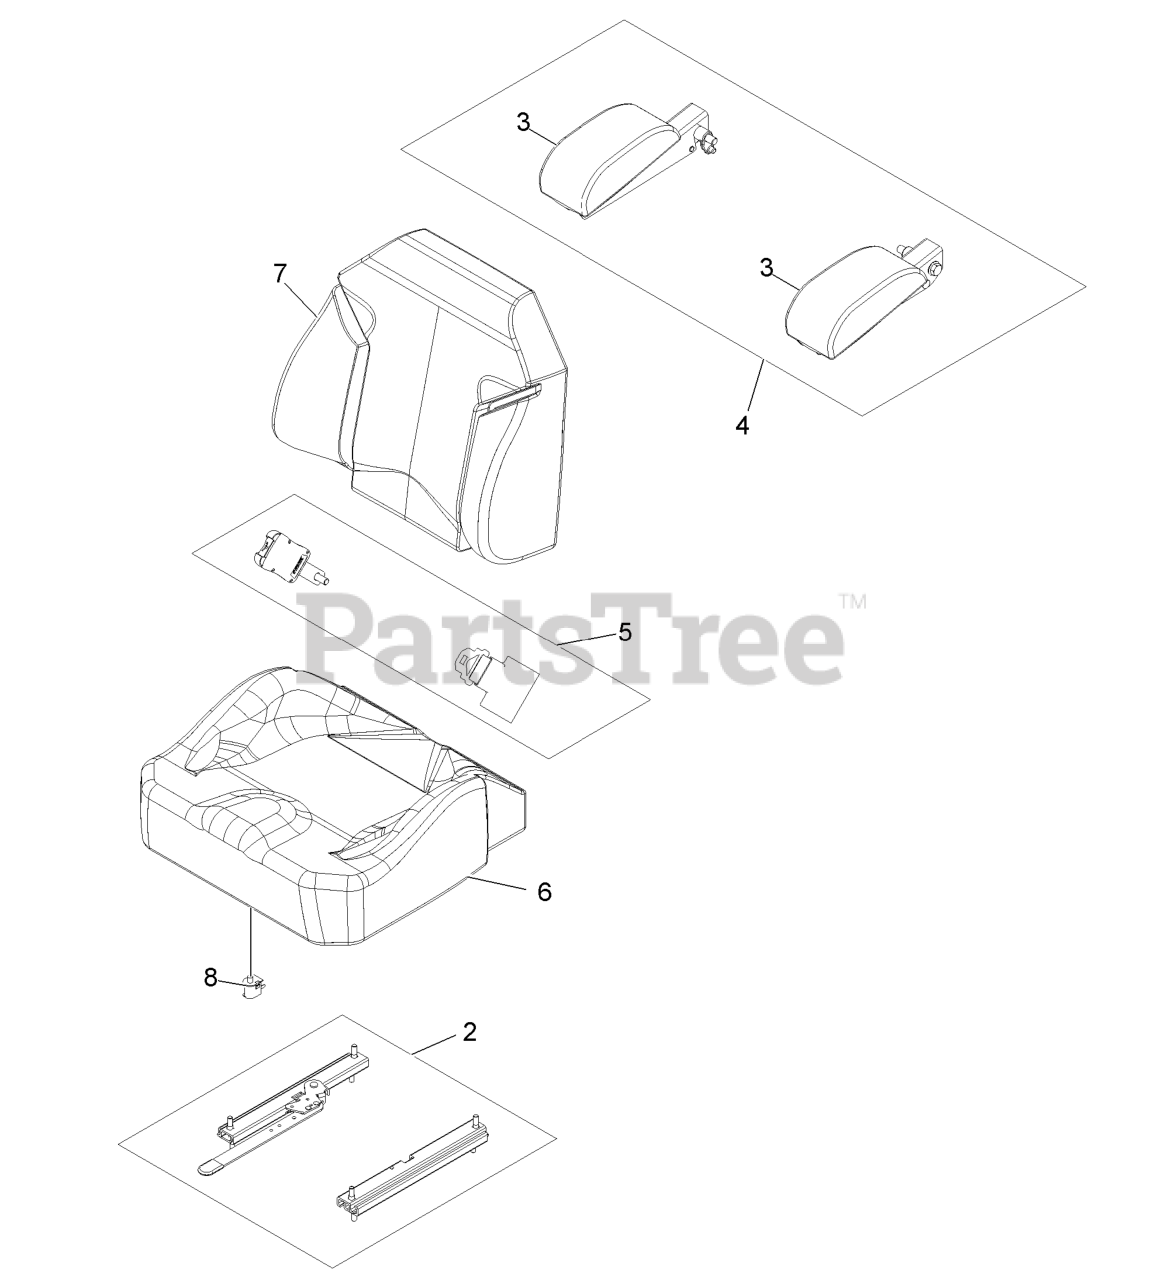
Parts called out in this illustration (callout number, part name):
2	SEAT TRACK SET
3	ARM REST PAD SET
4	ARM REST SET
5	SEAT BELT KIT
6	COVER,CUSHION
7	COVER,BACK
8	SWITCH-BAIL
